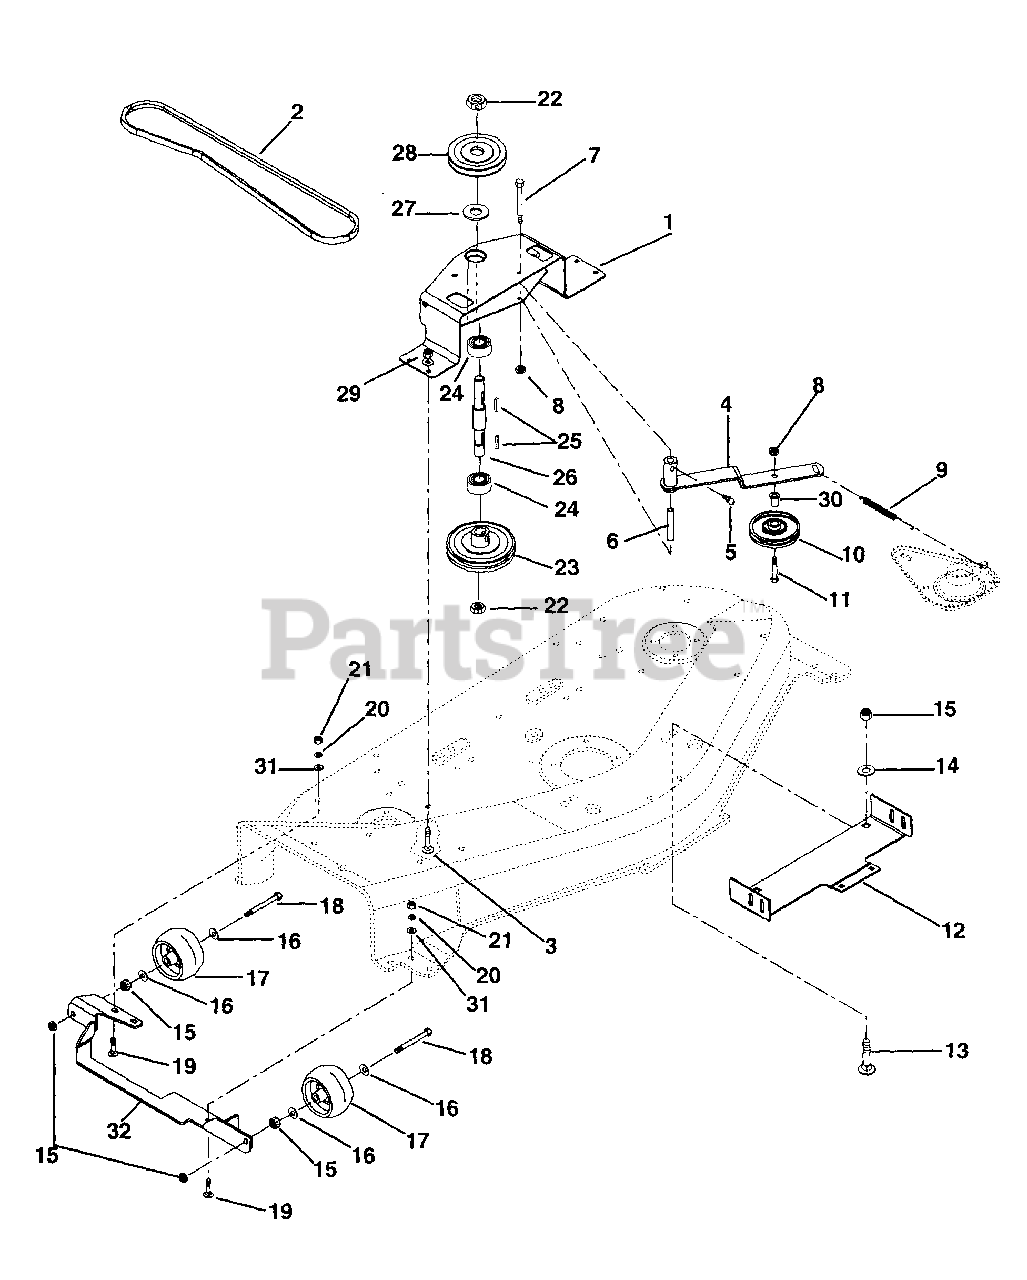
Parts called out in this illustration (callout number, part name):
1	Housing-Jackshaft
3	Bolt-Round Head Square Neck .31-18 x .75
4	Arm-Idler
5	Fitting-Lube .25-28 x .256
6	Spacer .385 ID x .625 OD x 2.73
7	Bolt-Hex .31-18 x 3.50 Grade 5
8	Nut-Locking-Center .38-16
9	Spring-Tension .113 x .812 x 7.00
10	Idler-Plastic 4.75 OD x.50 ID
11	Bolt-Hex .38-16 x 1.50 Grade 5
12	Brace-Front
13	Bolt-Round Head Square Neck .50-13 x .75 Grade 5
14	Washer-Flat-Steel .505 x .880 x .072
15	Nut-Locking-Center .50-13
16	Washer-Flat-Nylon .52 x 1.00 x .08
17	Wheel 5 x 3
18	Bolt-Hex .50-13 x 4.00
19	Bolt-Round Head Square Neck .31-18 x 1.00
20	Washer-Lock .312 x .097
21	Nut-Hex .312-18 Grade 2
22	Nut-Locking-Nylon .75 - 10 Grade 2
23	Pulley-V 6.00 x .75 w/Key
24	Bearing-Ball .750 x 1.781 x .61
25	Key-Square .187 x .50 x .187
26	Jackshaft
27	Washer-Flat-Steel .755 x 1.250 x .125
28	Sheave
29	Nut-Locking-Nylon .312-18 Grade 2
30	Spacer-Flanged .390 x .500 x .781 x .875
31	Washer-Flat-Steel .38 x .875 x .083
32	Mount-Roller
33	Washer-Flat .281 x .620 x .065
34	Nut-Center Locking .250-20
